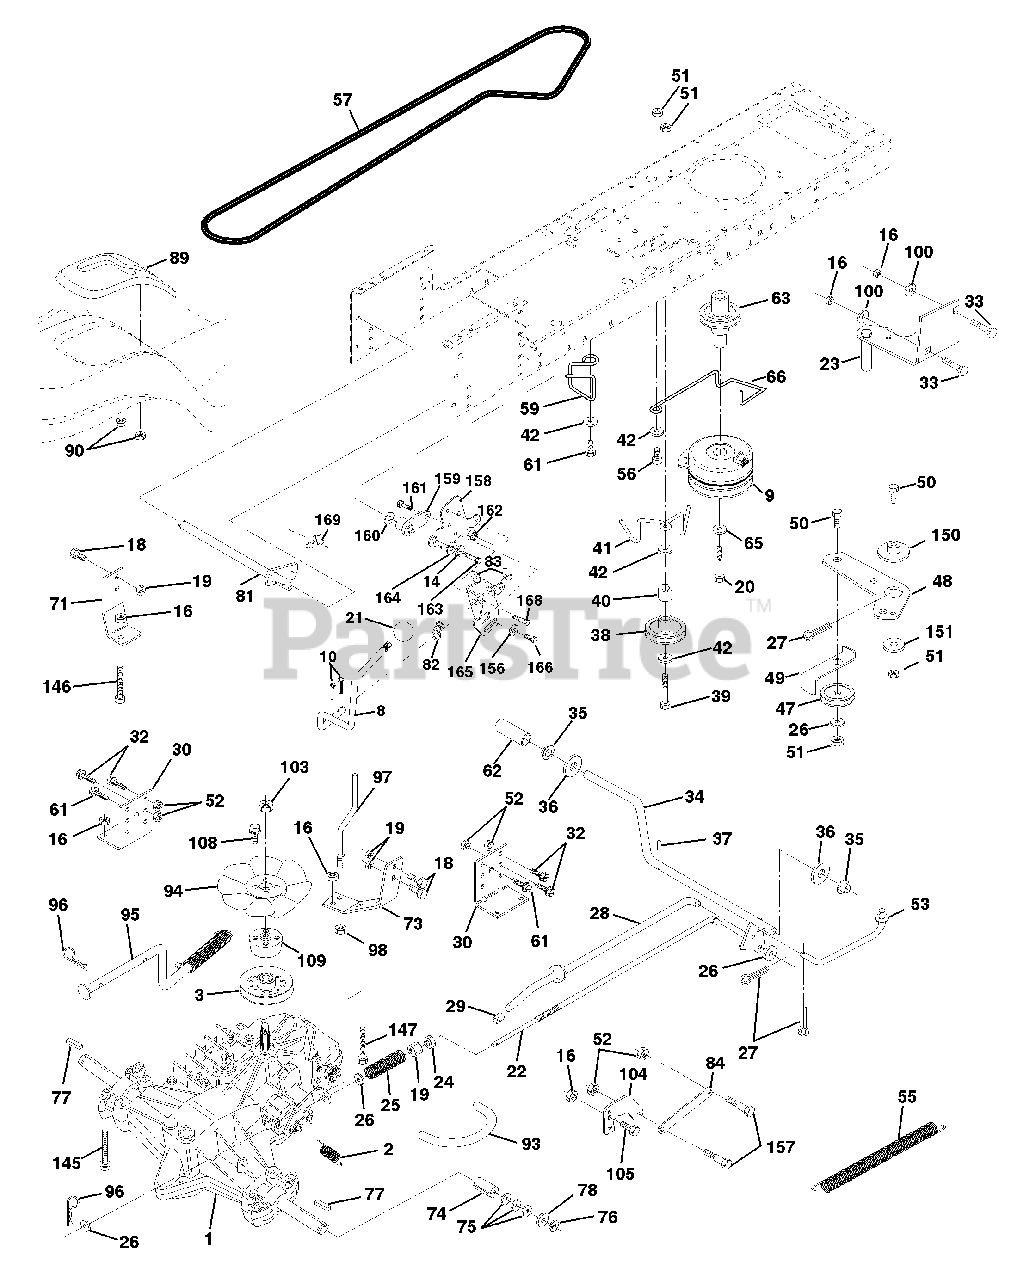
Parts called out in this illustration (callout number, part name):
1	Transaxle Hydro Gear, Model No. 319-0500
2	Spring, Return, Brake
3	Pulley, Transaxle
8	Rod Shift Fender Adjust
9	Clutch, Elect. EVX LT Mag 5217-2
10	Pin Cotter 1/8 x 1 CAD
14	Washer Lock Hvy Helical
16	Nut Lock Hex W/Ins. 5/16-18 Unc P
18	Bolt Fin Hex 3/8-16 Unc x 1 Gr. 5
19	Nut Lock Hex W/Wsh 3/8-16 Unc
20	Bolt Hex 7/16-20 x 4-1/4 Ga. 1.38
21	Knob, Duckhead 1/2-13
22	Rod, Brake Hydro
23	Bracket, Asm Clutch Mtg EVX
24	Nut
25	Spring, Brake Rod
26	Washer
27	Pin Cotter 1/8 x 3/4 CAD.
28	Rod, Parking Brake
29	Cap, Parking Brake
30	Bracket, Transaxle
32	Bolt Hex Hd 5/16-18 Unc x 3/4
33	Bolt Rdhd Sqnk 5/16-18 UNC x 3/4
34	Shaft, Foot Pedal
35	Bearing, Nylon
36	Washer
37	Pin, Roll
38	Pulley, Idler, Flat
40	Spacer, Split
41	Keeper, Belt Idler
42	Washer 13/32 x 13/16 x 12 Gauge
47	Pulley, Idler, V-Groove
48	Bellcrank Assembly
49	Retainer, Belt
50	Bolt
52	Nut Crownlock 5/16-18
53	Link, Clutch
55	Spring, Return, Clutch
56	Bolt Fin Hex 3/8-16 UNC x 1-1/4
59	Keeper, Center Span
61	Screw Thdrol. 3/8-16 x 3/4 Ty. TT
62	Cover, Pedal
65	Washer
66	Keeper Belt Engine Full-Proof
71	Strap Torque Lh Hydro
73	Strap Torque Rh Hydro
74	Spacer, Split
75	Washer 25/32 x 1-1/4 x 16 Gauge
77	Key, Square
78	Washer 25/32 x 1-5/8 x 16 Gauge
81	Shaft Asm Cross Tapered
82	Spring Torsion
83	Washer 17/32 x 3/4 x 16 Ga.
84	Link Transaxle
86	Bushing Rod Steering 629/632 ID
87	Washer 21/32 x 1-1/4 x 16 Ga.
88	Ring Klip #5304-62
89	Console, Shift
90	Nut, Self-Thd Wsh-hd 1/4 Zinc
93	Line Fuel Hydro 4"
94	Fan, Hydro 7"
95	Control Asm Bypass Hydro
96	Retainer Spring 1" Zinc/Cad
97	Keeper Belt Rh Hydro
98	Nut Keps Hex 3/8-16 Unc
100	Washer 11/32 x 3/4 x 16 Ga.
103	Nut Nylon Insert 1/2-20 Unf.
104	Arm, Control Hydro
105	Screw Cap Hex 5/16 x 18 x 1
106	Bolt Fin Hex 5/16-18 Unc x 1-1/4
108	Screw Hex Wh Hd #10-24 x
109	Adaptor Fan Hydro LT Hyd Alum
144	Washer 11/32 x 5/8 x 16 Ga.
145	Bolt, Hex Flghd 5/16-18 Gr. 5
146	Bolt Fin Hex 5/16-18 x 2-1/4
147	Bolt Fin Hex 5/6-18 Unc x 1-1/2
150	Bushing Bellcrank Grd Drive
151	Washer 13/32 x 2 x 10 Ga.
156	Washer Srrted 5/16 ID x 1 .125
157	Bolt Shoulder 5/16-18 Unc- 2A
158	Bracket Shift Mount
159	Hub Tapered Flange Shift Lt
160	Washer 29/32 x 1-1/4 x 16 Ga.
161	Bolt Rdhd Sqnk 1/4-20 x 3/4 Gr. 5
162	Nut Crownlock 1/4-20 Unc
163	Bolt Hex Fin 1/4-20 Unc x 1 Gr. 5
164	Washer 5/8 x .281 x 10 Ga
165	Bracket Pivot Lever
166	Screw 5/16-18 x 5/8
168	Bolt Shoulder 5/16-18 x .561
169	Plate Fastening
